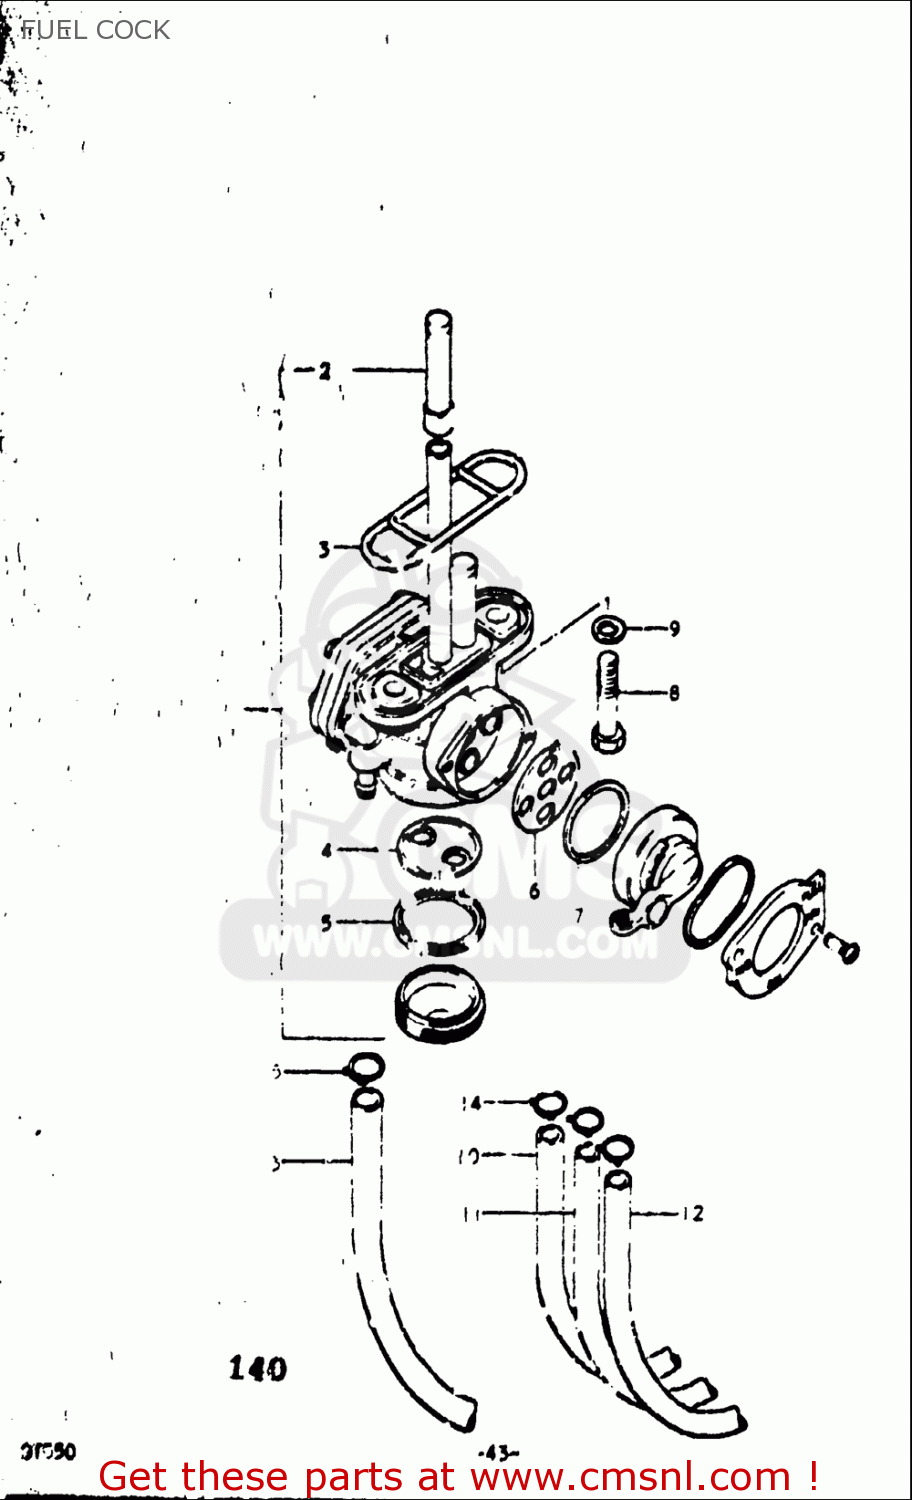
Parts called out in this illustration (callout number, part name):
1	COCK ASSY,FUEL
2	FILTER
3	GASKET, FUEL COCK (NAS)
4	FILTER,CUP
5	GASKET,CUP (NAS)
6	GASKET (NAS)
7	V SEAL,FUEL COCK
8	BOLT
9	GASKET(5.8X13X1.2) (NAS)
10	HOSE(5X8.2X2000)
11	HOSE(5X9X600)
12	HOSE(5X8.2X600)
13	HOSE(7X10.2X2000)
14	CLIP
15	CLIP
